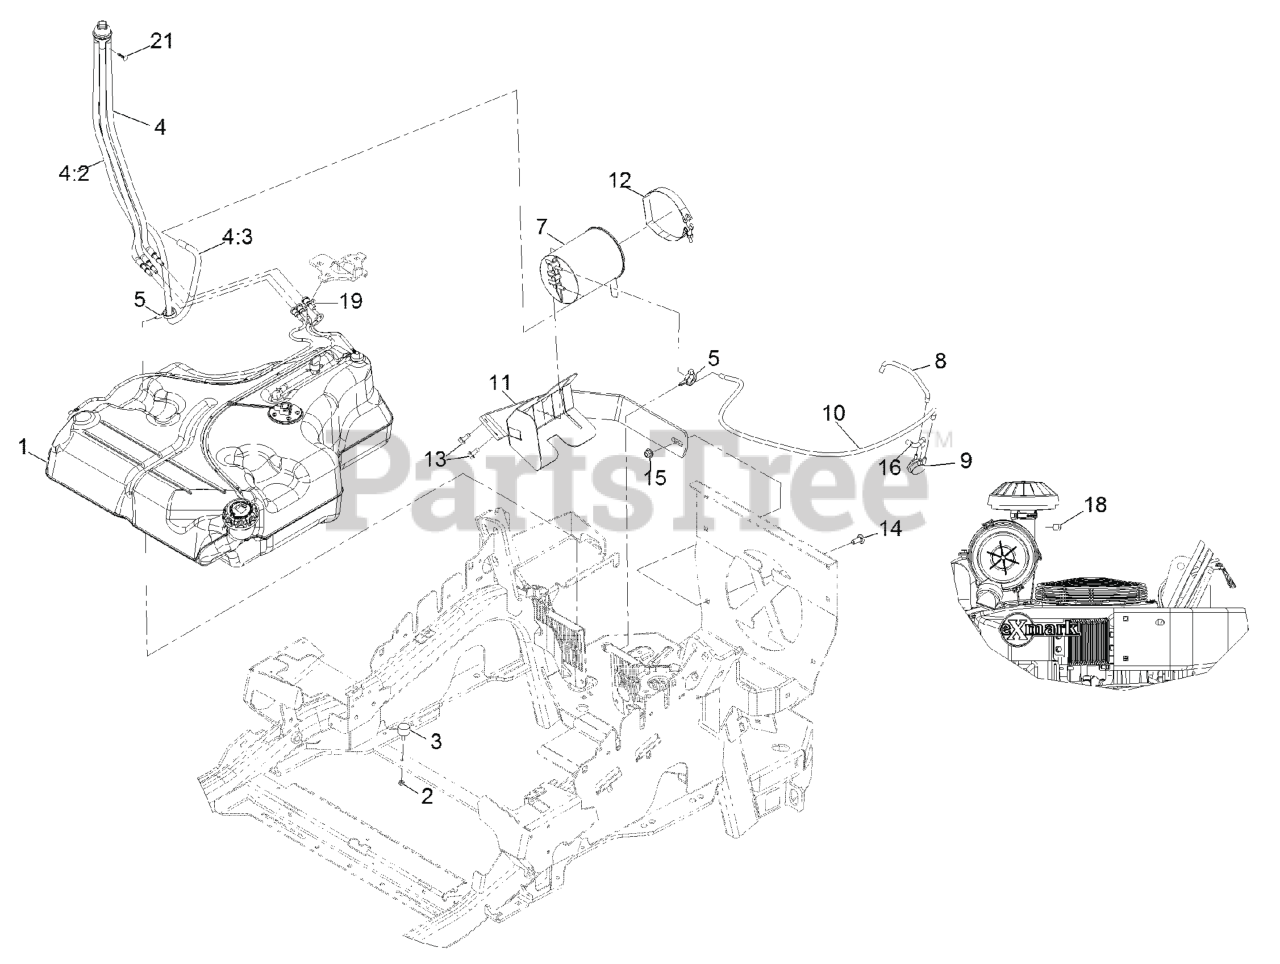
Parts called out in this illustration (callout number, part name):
1	ASM-8 GALLON FUEL TANK
2	NUT-JAM
4	FUEL MANIFOLD VENT ASM
4:2	HOSE-FUEL
4:3	HOSE-FUEL
5	CLAMP-HOSE
7	CANISTER-CARBON, 1200CC
8	BRACKET-VALVE MOUNT
10	GROMMET
11	MOUNT-CANISTER
12	CLAMP, T-BOLT
13	Screw-HWH 5/16-18 X 3/4 Tf
14	SCREW-CARR
15	NUT-HF, NI
16	TIE-PLASTIC
17	SCREW-HHF
18	PLUG-PORT
19	RETAINER-LINE, VAPOR
21	PLUG-PLASTIC
22	WASHER-SPRING
23	HOSE-FUEL
24	HOSE-FUEL
25	Hose-Fuel
26	FITTING-STRAIGHT
